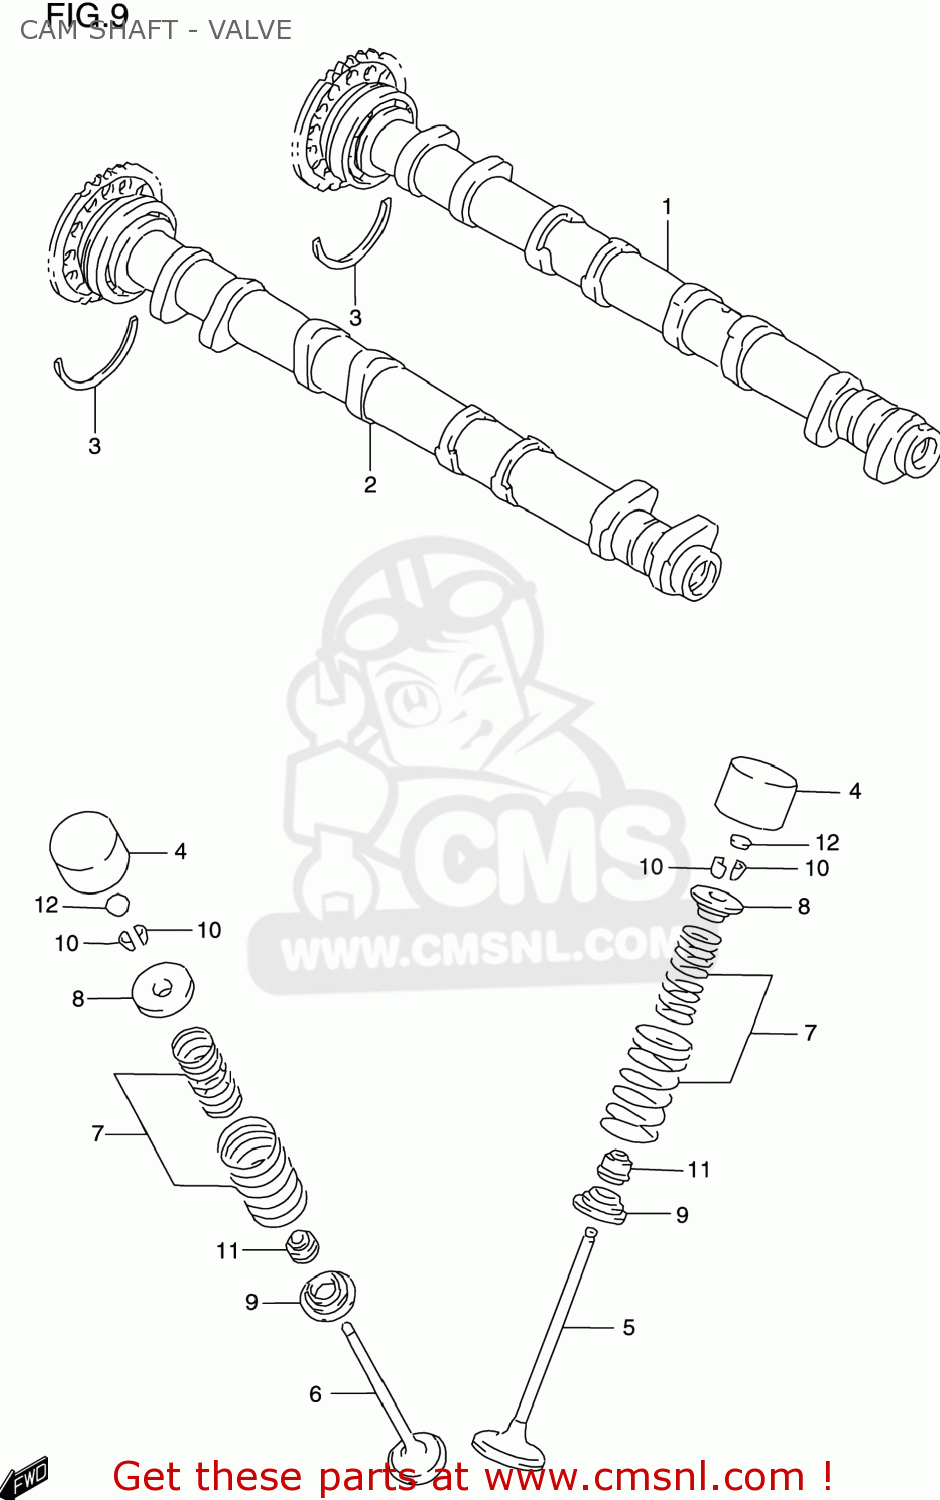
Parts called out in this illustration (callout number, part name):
1	CAMSHAFT,INTAKE
2	CAMSHAFT,EXHAUST
3	C RING
4	TAPPET
5	VALVE,INTAKE
6	VALVE,EXHAUST
7	SPRING SET,VALVE
8	RETAINER,VALVE SPRING
9	SEAT,VALVE SPRING
10	COTTER VALVE
11	SEAL,OIL(4.5X10X8)
12	SHIM,TAPPET
13	SHIM SET,TAPPET
14	CASE,TAPPET SHIM
